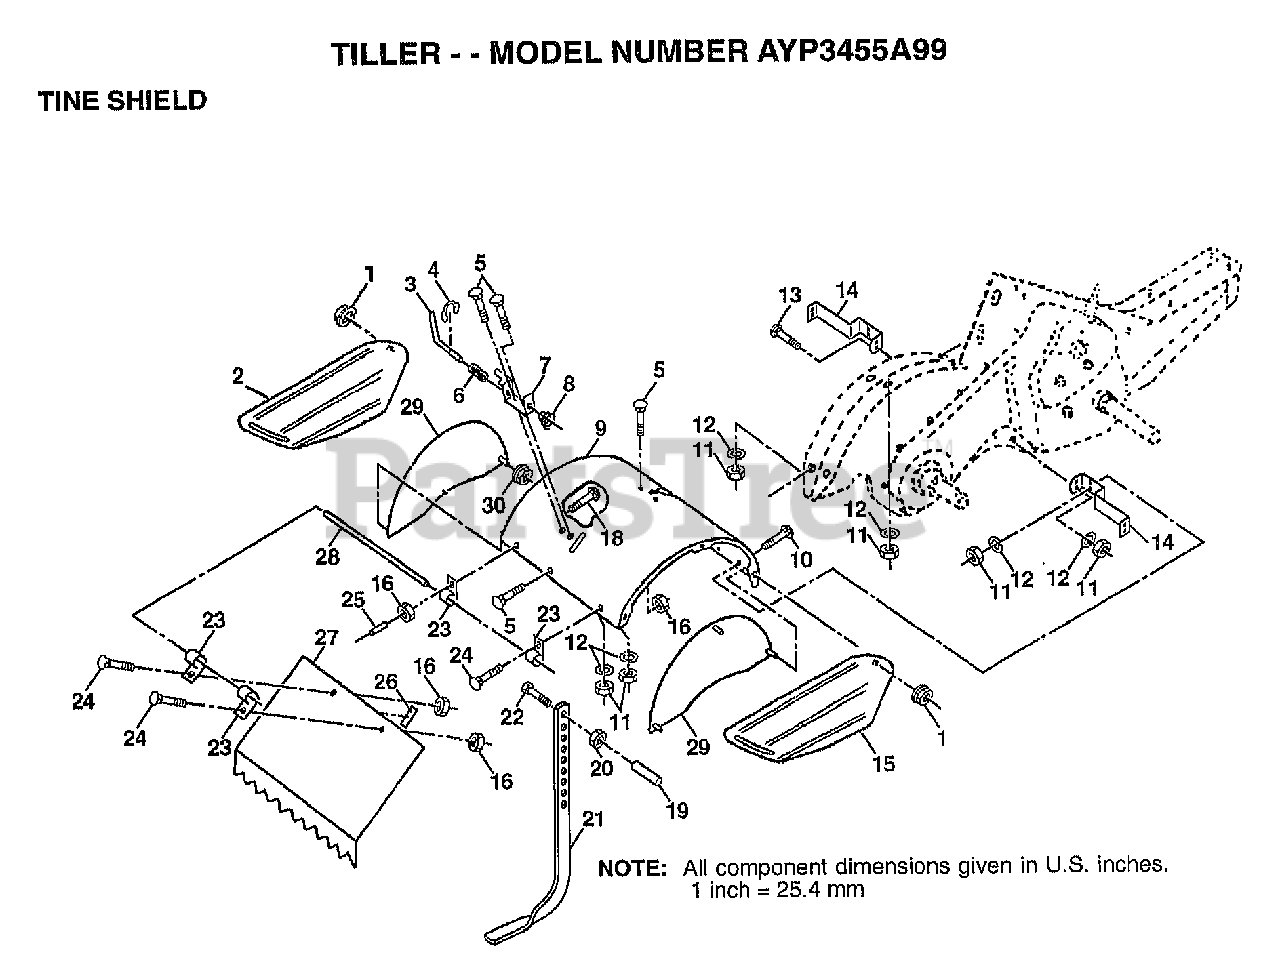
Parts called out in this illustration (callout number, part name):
1	NUT
2	"SHIELD,SIDE,O.LH"
3	STAKE PIN TI
4	KLIP RING TI
5	BOLT
6	SPRING TI
7	LATCH BRACKET TI
8	SPRING CRT
9	TINE SHIELD
10	BOLT
11	NUT.HEX.5/16-18
12	LOCKWASHER
13	BOLT
14	"BRACKET,SHIELD"
15	SHIELD SIDE O.RH
16	NUT
18	BOLT
19	GRIP CRT
20	NUT.HEX.3/8-16UNC
22	BOLT
23	HINGE CRT
24	BOLT
25	VINYL CAP TI
26	PAD IDLER TI
27	LEVELING SHIELD
28	PIN HINGE
29	SIDE SHIELD
30	LOCKNUT TI
